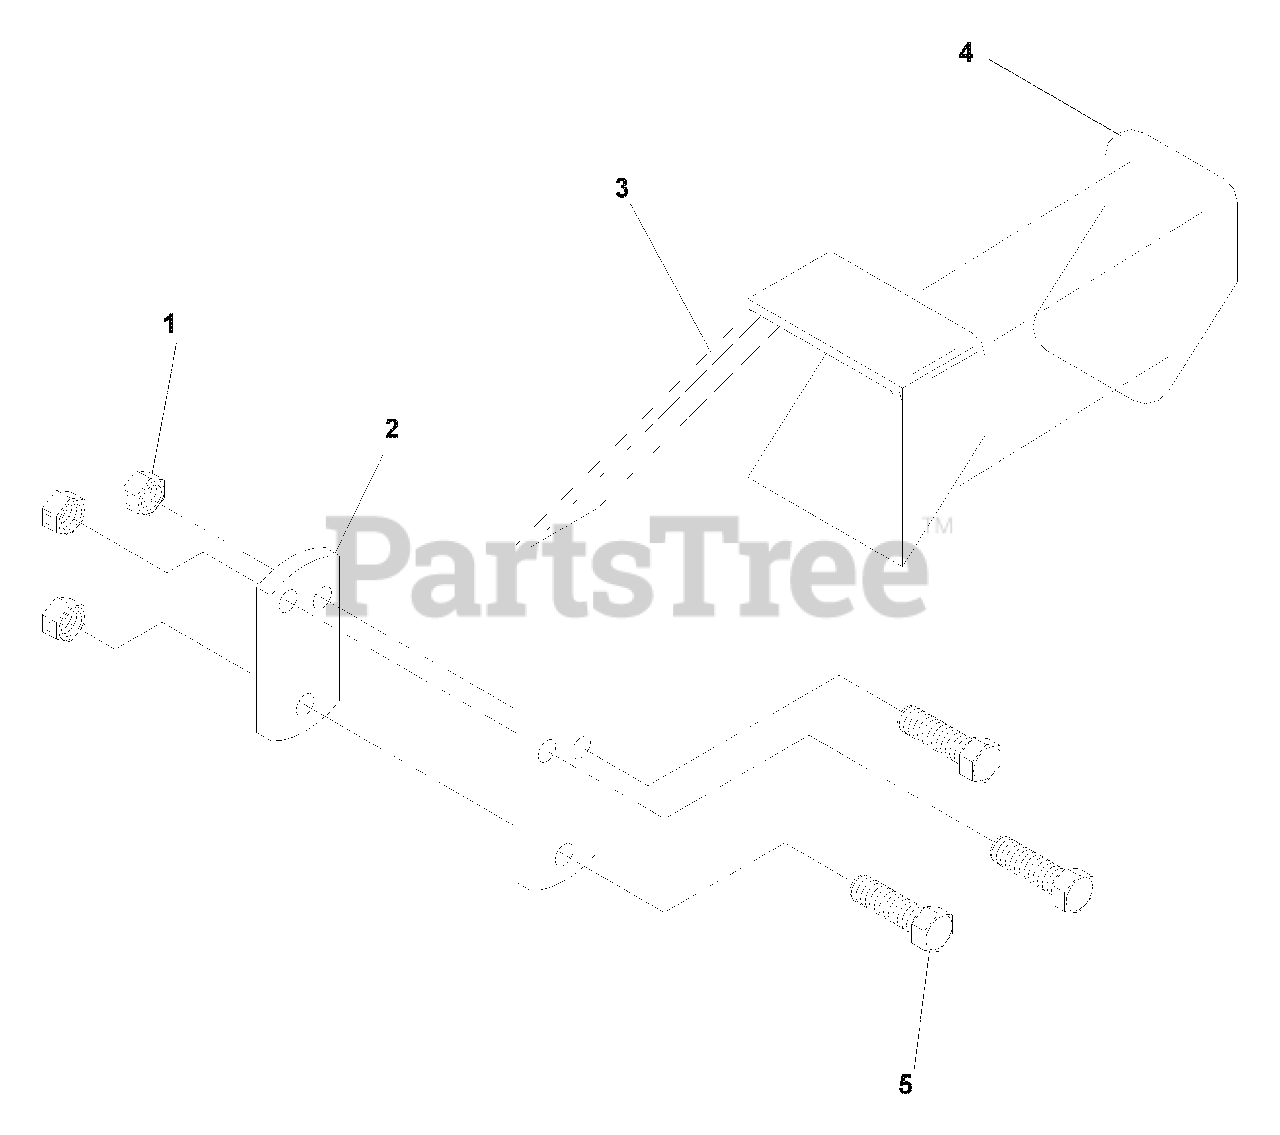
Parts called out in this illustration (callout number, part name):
1	Nut, 3/8-16, nyloc
2	Plate, tighting
3	Pedal, lift
4	Pad, anti-skid
5	Bolt 3/8-16 x 1 1/2
